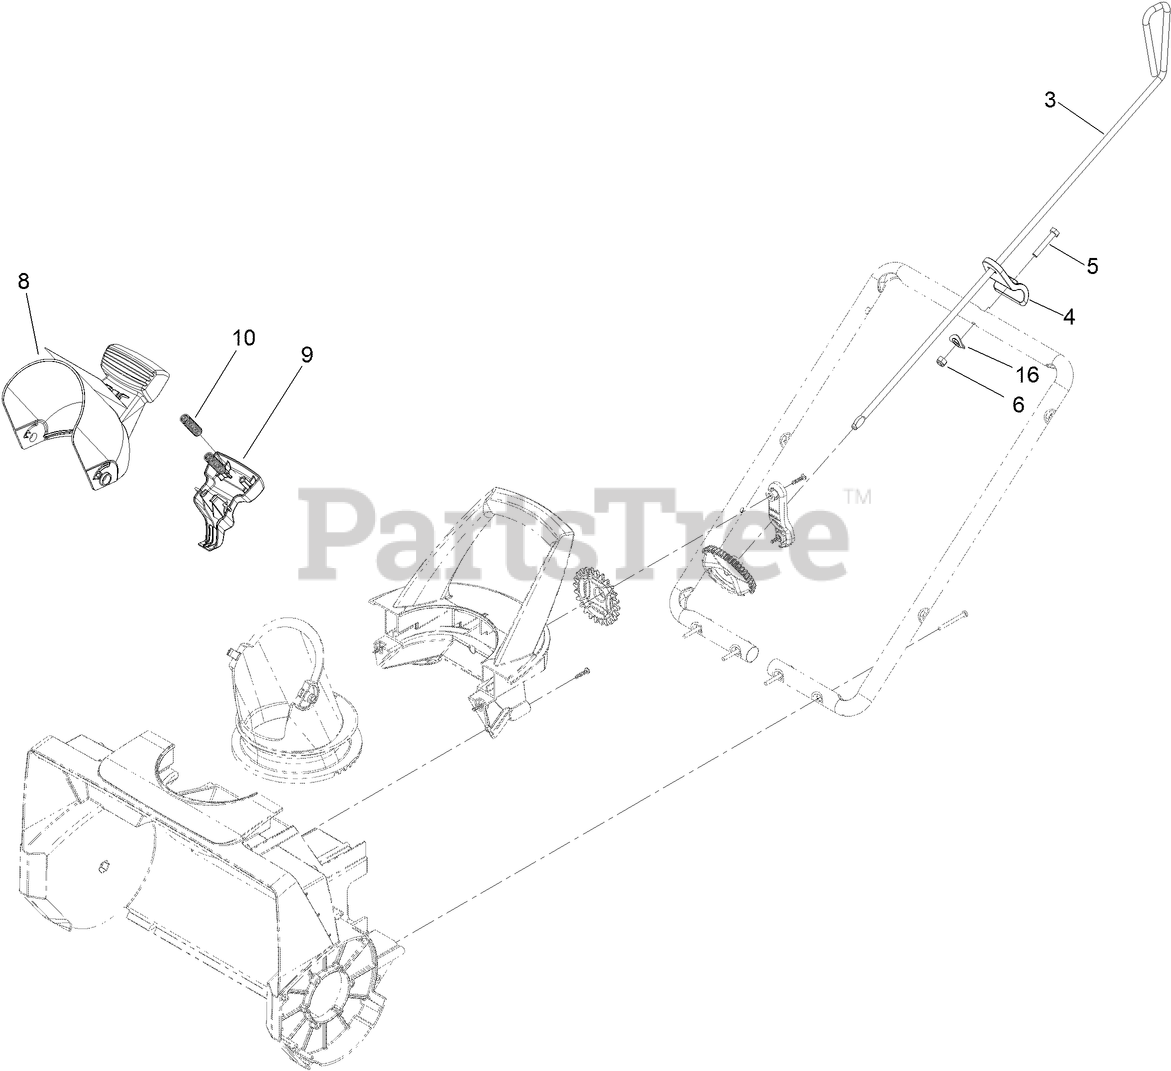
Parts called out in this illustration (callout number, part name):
3	ROD-CONTROL, CHUTE
4	GUIDE-ROD, CHUTE
5	SCREW-HH
6	NUT-LOCK, NI
8	CHUTE DEFLECTOR ASM
9	TRIGGER-DEFLECTOR
10	SPRING-COMPRESSION
16	WASHER
